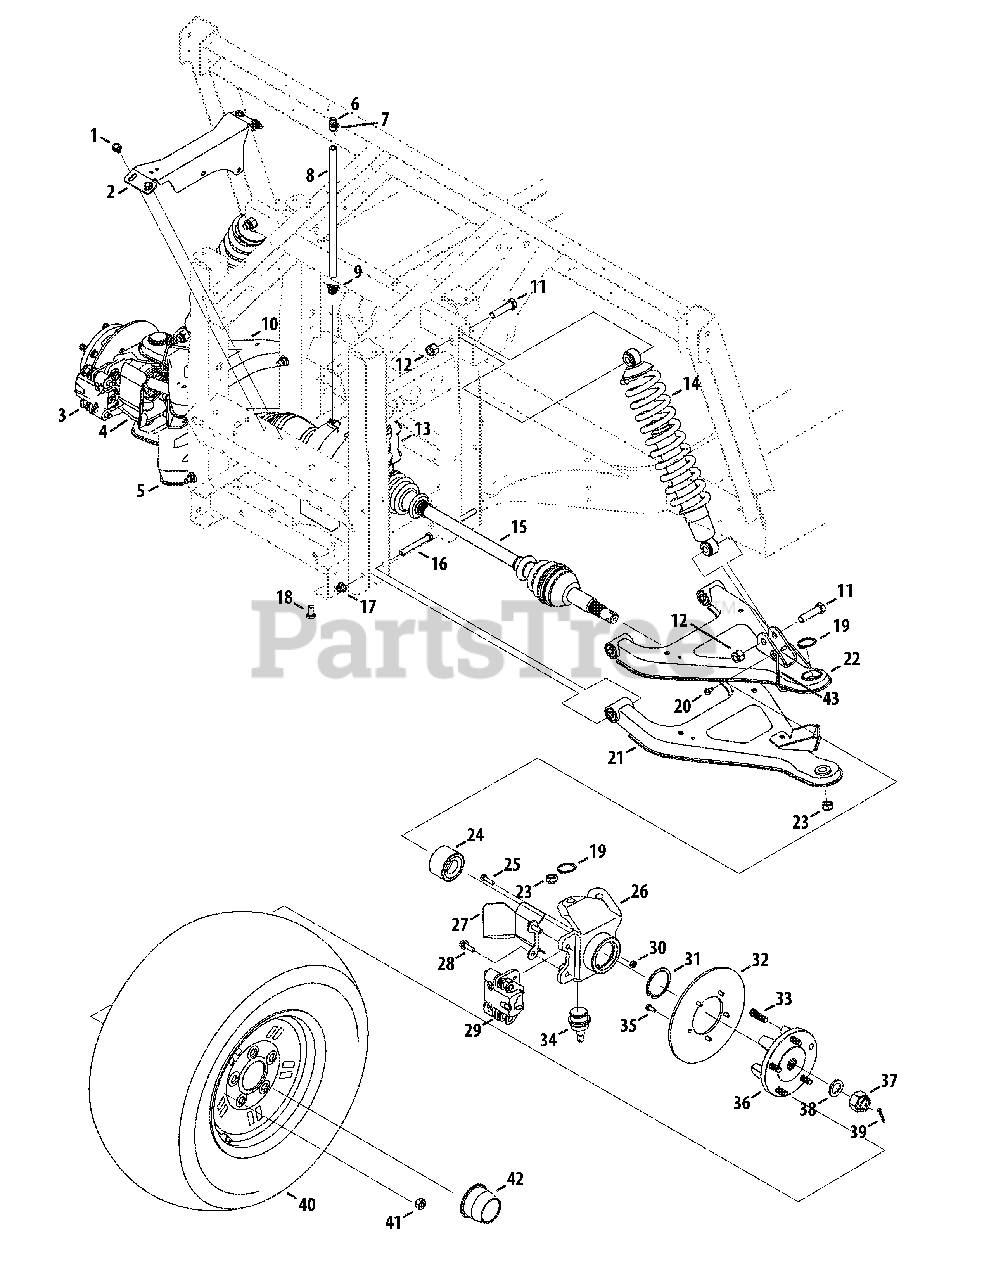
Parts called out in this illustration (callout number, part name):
1	Screw, tt, 5/16-18 x 0.500
2	Front Mount, differential, 4x4
3	Brake, hydraulic, caliper, frt, RH
4	Housing, knuckle, r/frt, mach
4	Knuckle Kit, Front, R & L
5	Control Assembly, r/frt, lower
6	Vent,3/8 Dia
7	Clamp, hose, .490 Dia.
8	Hose, Fuel Line
9	Clamp, Hose, Adj.
10	Arm Assembly, r/frt, upper
11	Screw, 1/2-13 x 2.00, gr5, std
12	Nut, Hex Lock, 1/2-13, Nylon
13	Differential Assembly, cfd, 4x4
14	Shabs, 5.0 Stroke, front
15	Axle Assembly, CV Joint, 4x4
16	Screw, 3/8-16 x 3.00, gr8, std
17	Nut, Flange Lock, 3/8-16, Nylon
18	Screw, 3/8-16, .75, gr5, std
19	Ring, retainer, 34 x 1.6
20	Screw, tt, 1/4-20 x .500
21	Control Assembly, l/ftr, lower
22	Control Assembly, l/frt, upper
23	Nut, Nylock, m12 x 1.25
24	Bearing, dble Row, 60x30x37
25	Screw, 1/4-20 x 1.00, gr5, spec
26	Housing, knuckle, l/frt, mach
26	Knuckle Kit, Front, R & L
27	Bracket, Steering Shield, LH
27	Bracket, Steering Shield, RH
28	Screw, m8-1.25, 25.00
29	Brake, hydraulic, caliper, frt, LH
30	Nut, Hex, 1/4-20, gr5
31	Ring, retainer, dho-60
32	Disc, brake, 8.00x.188
33	Stud, rib Neck, 7/16-14 x 1.6
34	Ball Joint, 14d-6201
35	Screw, 1/4-20 x .625, gr5, lock
36	Hub, wheel
37	Nut, slotted, 22x1.5
38	Washer, flat, .88 x 1.38 x .125, ht
39	Pin, cotter, 5/32, 1.25
40	Wheel Assembly, RH, 25 x 10-12
40	Wheel Assembly, RH, 25x 10-12
40	Wheel Assembly, LH, 25 x 10-12
41	Nut, lug, 7/16-14
41	Nut, lug, 7/16-14, Chrome
42	Cap, Wheel
42	Cap, Wheel, Chrome
43	Wire, Brake Line
